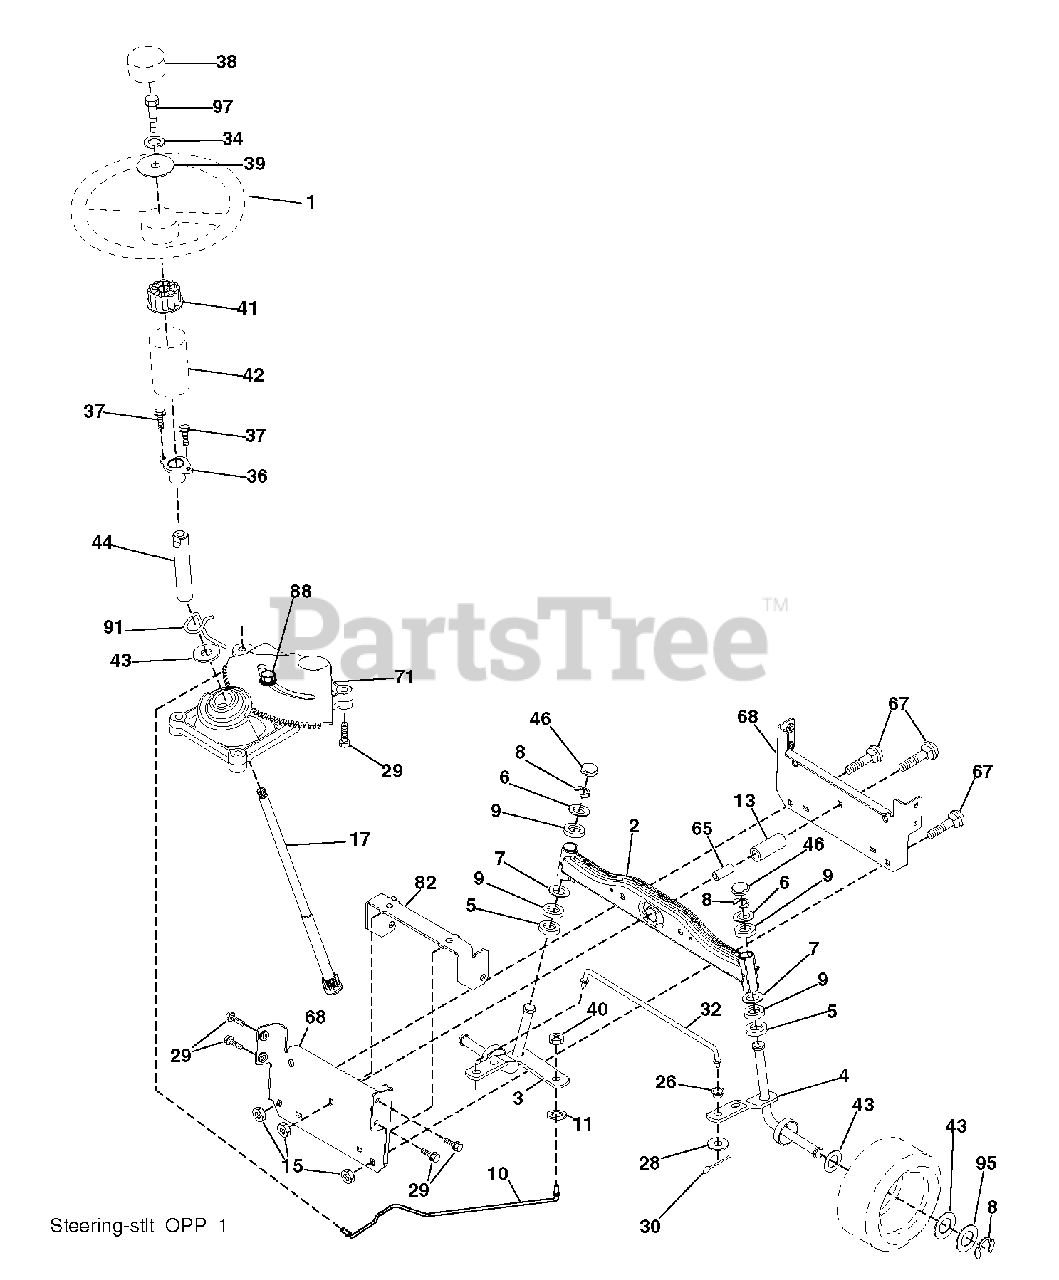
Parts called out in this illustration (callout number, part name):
1	WHEEL.STEERING.OPP.BLACK
2	AXLE HALF ASM-WELDED
3	SPINDLE.ASM.LH.15"TIRES
4	SPINDLE.ASM.RH.15"TIRES
5	THRUST WASHER
9	BRNG T
10	DRAGLINK.15".TIRES.2001
11	WASHER, LOCK 3/8
13	TUBE, PIVOT AXLE (2 2)
15	NUT LOCK FLG 3/8-16 UNC
17	SHAFT STEERING SPLINE
26	BUSHING.DRAGLINK (2 2)
28	WASHER
29	SCREW, 3/8-16X3/4
30	COTTER PIN
32	ROD.TIE.WIRE.FORM
34	LOCKWASHER
36	BUSHING, STEERING
37	SCREW.TT.#10-32X.5.3/8.FLANGE
38	CAP.WHEEL.STEER.OPP.BLK
39	WASHER.11/32
40	NUT CROWNLOCK 3/8-24
41	ADAPTER, WHEEL STNG..
42	BOOT.STEERING.SHAFT.BLACK
44	SHAFT.EXTEN.STRG.SPLINE
46	CAP.SPINDLE.BLACK
65	SPACER.BRACE.AXLE
67	BOLT CARRIAGE
68	BRACE.AXLE.15"TIRES
71	STEERING ASM
82	BRACKET.SUSP.CHASSIS.FRONT.15
88	BOLT, SHOULDER 7/16-20
91	CLIP.STEERING
95	WASHER.HARDENED
97	BOLT 5/16-18 X 4 W/PATCH
